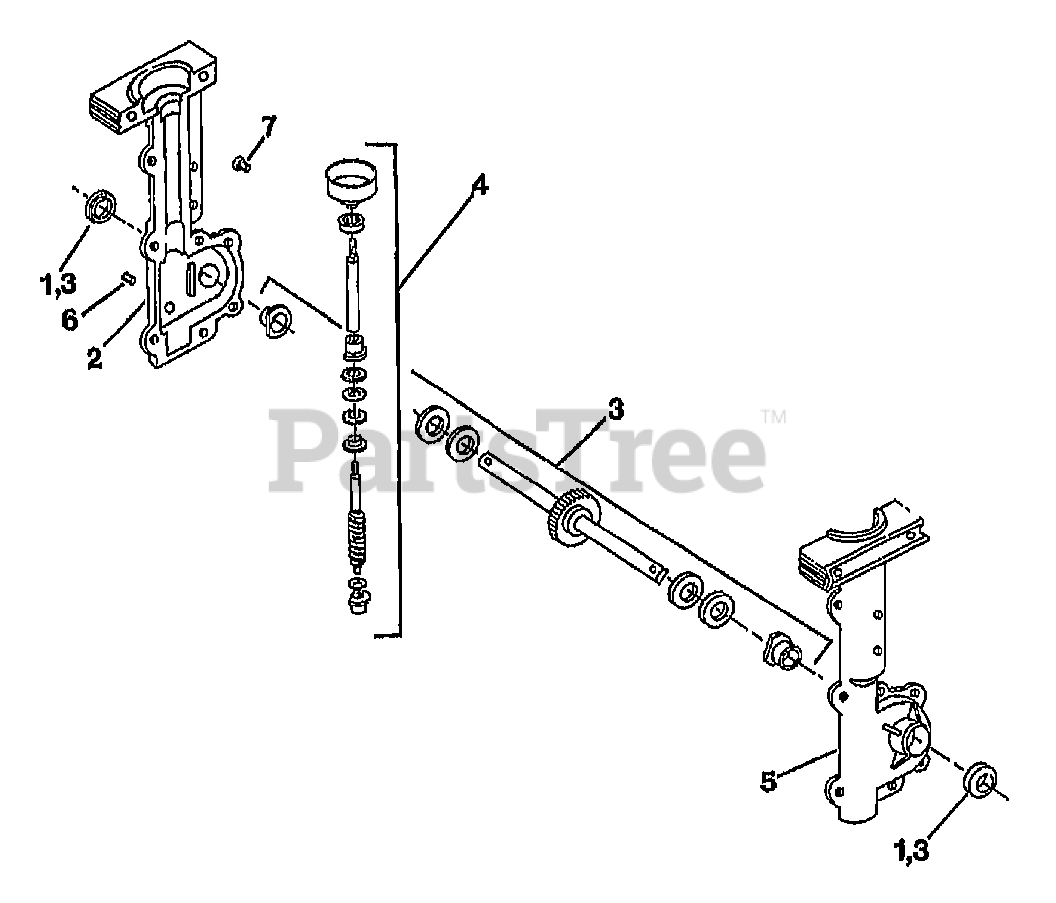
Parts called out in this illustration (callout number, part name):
2	TRANSNISSION, RIGHT HAND HALF
2	ASSM-TRANSMISSION SPDY HOE
3	KIT-TINE SHAFT (INCL. TWO 1 & 3)
4	INPUT SHAFT ASM KIT-HHT
5	TRANSMISSION LEFT HAND HALF
5	ASSM-TRANSMISSION SPDY HOE
6	PLUG-OIL FILL HHT
7	SCR-PHP M10-32X.38 STH ZP
